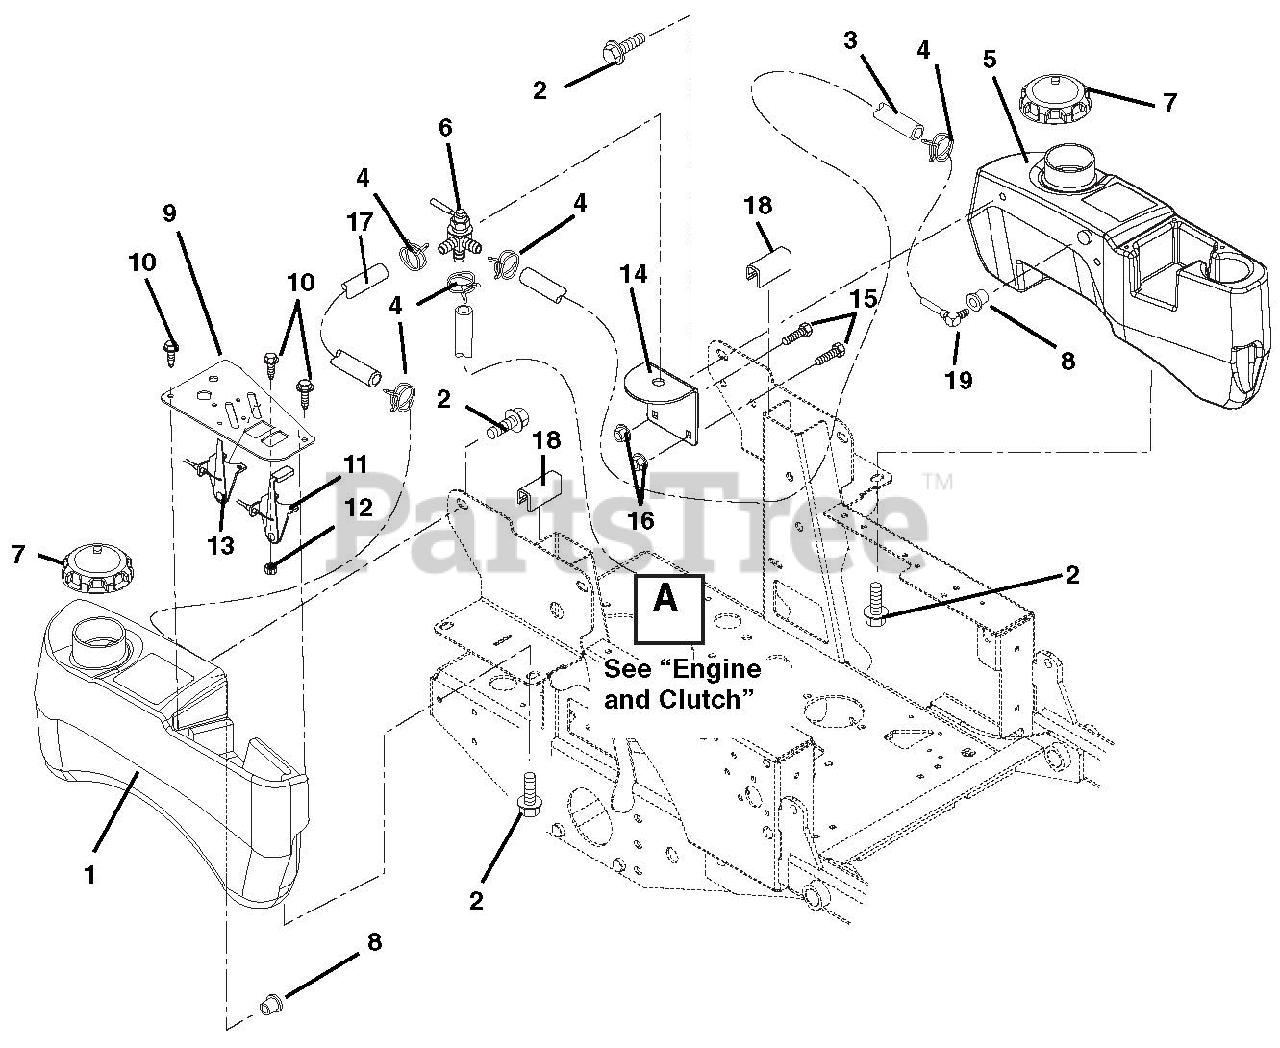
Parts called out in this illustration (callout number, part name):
1	Tank, Gas- Right Hand
2	Bolt, SEMS .31-18 x .62
3	Hose, Gas Line 6.25"-.25" I.D.
4	Hose, Clamp
5	Tank, Left Hand Fuel (Eye-Q)
6	Valve, Fuel
7	Cap, Fuel
8	Grommet
9	Panel, Control
10	Screw, Machine 10-24 x .50 Hex Washer Head
11	Cable, Throttle Choke
12	Nut, Locking Nylon 10-24 With Insert
13	Cable, Choke
14	Bracket, Fuel Valve Mounting
15	Bolt, Round Head Square Neck .31-18 x .75 Grade 5
16	Nut, Nyloc Flange 5/16-18
17	Hose, Gas Line 29"-.25" I.D.
18	Cowl Strip 1.75" Long
19	Assembly, Large Tank Fuel Pick-up
